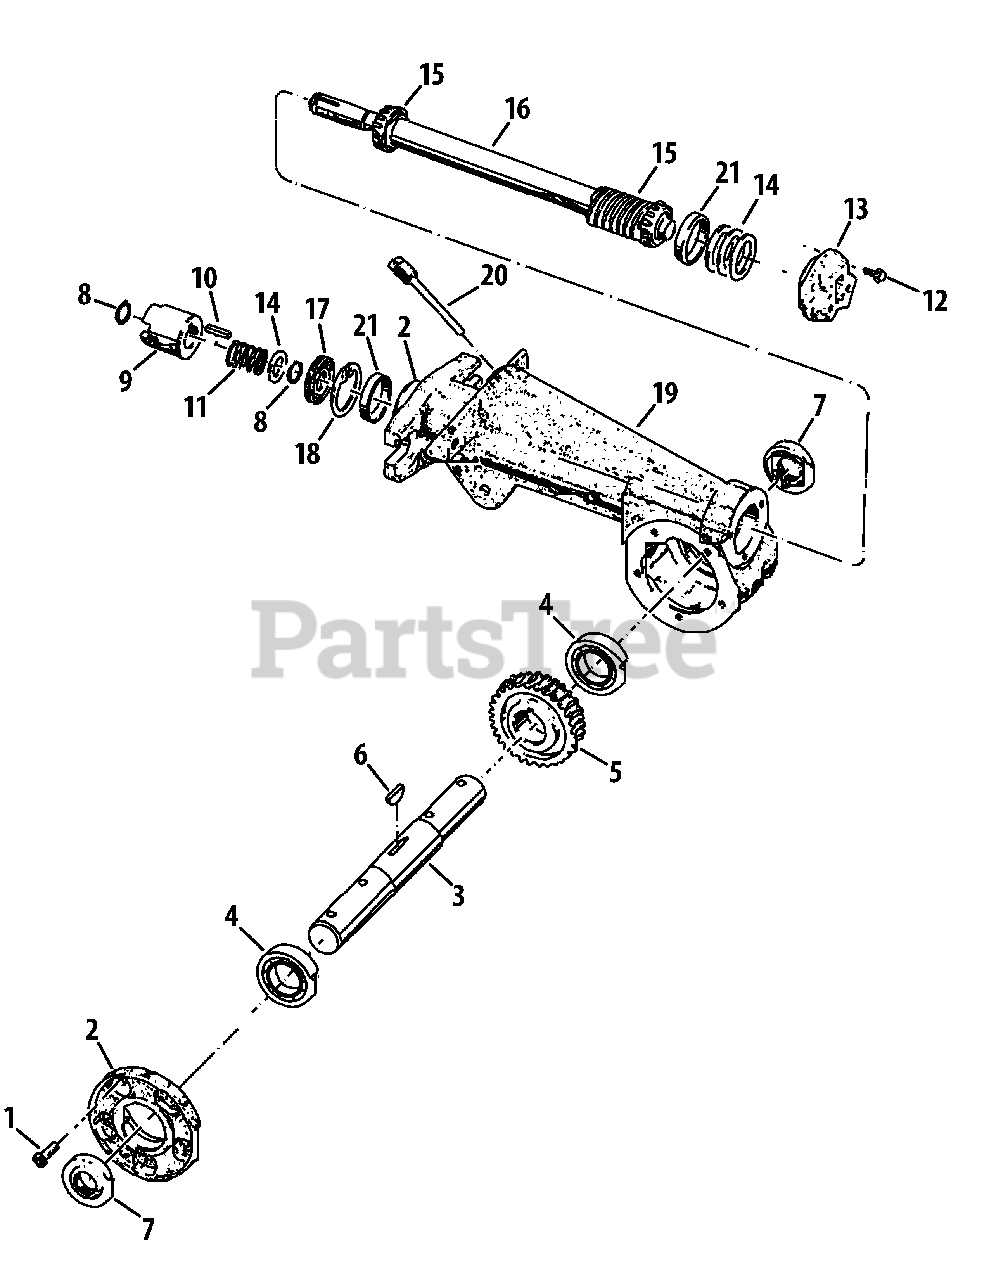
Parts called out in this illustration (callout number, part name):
1	Self-Sealing Screw, 1/4-20 x 5/8"
2	Tiller Housing Cover
3	Tine Shaft
4	Ball Bearing
5	Worm Gear
6	Woodruff Key
8	External Retaining Ring
9	Dog Clutch
10	Key, 3/16" x 1"
12	Self-Sealing Screw, 1/4-20 x 7/8"
14	Flat Washer, 1.75 x 1.5 x .062
14	Flat Washer, 1.75 x 1.5 x .005
14	Flat Washer, 1.75 x 1.5 x .03
14	Flat Washer, 1.75 x 1.5 x .01
15	Cone Bearing
18	Retaining Ring
19	Attachment Housing
20	Oil Dipstick
21	Cup Bearing
